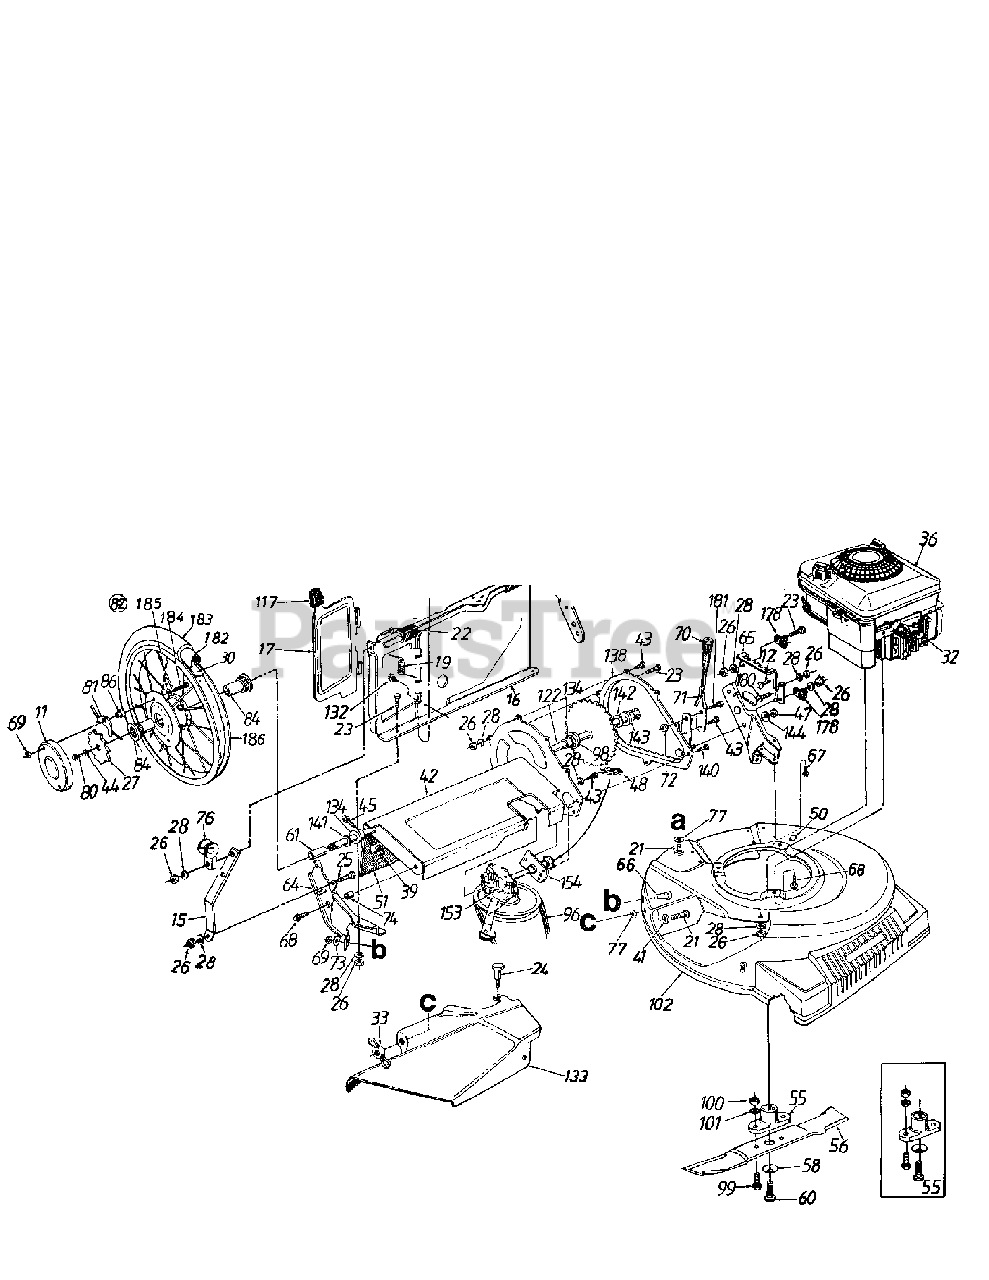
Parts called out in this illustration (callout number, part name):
1	Grip
2	Control Handle Ass'y. L.H.
3	Rope Guide Bolt
4	Truss Mach. Scr. #12 x 1.50" Lg.
5	Rear Discharge Chute Ass'y.
6	3 Tooth Rack Gear Insert
7	Control Panel Half
8	Control Disc Pin
9	Clutch Panel Half
10	Throttle Control Lever
11	Wheel Cover
12	Truss Mach. Scr. 1/4-20 x .62" Lg.
14	Upper Handle
15	Panel Support Brkt.
20	Pivot Pin
21	Carriage Bolt 1/4-20 x .62"
22	Truss Mach. Scr. 1/4-20 x .75" Lg.
23	Hex Bolt 1/4-20 x .5" Lg.
24	Shoulder Bolt Special
25	Hex Bolt 1/4-20 x .62" Lg.
26	Hex Nut 1/4-20 Thd.
27	Wheel Ratchet
28	L-Wash. 1/4" I.D.
30	Rim Strip
31	S.P. Control Cover
32	Spark Plug Insulator
33	Wing Nut
34	Throttle Control Wire 61"
35	Lower Handle
36	Engine
38	Grass Bag
39	Retaining Strip
41	Fl-Wash. .344" I.D. x .62"
42	Rear Support Drive Ass'y.
43	Hex B-Tap Scr. 1/4" x .38"
44	Bell-Wash. 1/4" I.D.
45	Hex AB-Tap Scr. 1/4 x .62"
47	Hex Patch L-Nut 3/8-24 Thd.
48	#48 Chain .500" Pitch x 52 Links
51	Rear Flap
52	Cable Tie (w/Post)
54	Hex AB-Tap Scr. #12 x 1.25" Lg.
55	Blade Adapter Kit
56	21" Blade
58	Bell-Wash. .46" I.D.
60	Hex Bolt 7/16-20 x 1.5"
61	Spacer .628" I.D.
63	L-Wash. 5/16" I.D.
64	Handle Brkt. Ass'y. R.H.
65	Handle Brkt. Ass'y. L.H.
66	Carriage Bolt 5/16-18 x .62"
67	Hex B-Tap Scr. 5/16-18
68	Hex TT-Tap Scr. 3/8-16
69	Hex Nut 5/16-18 Thd.
71	Height Adj. Lever
72	Flanged L-Nut 3/8-16 Thd.
73	Bell-Wash. 5/16" I.D.
74	Spacer .383" I.D.
76	Rope Guide
77	Bolt Retainer 1/4 x .50" O.D.
79	Control Label
80	Hex Bolt 1/4-20 x .75" Lg. (Grade 5)
81	Pawl and Spring Ass'y.
82	Wheel Ass'y. Comp.
84	Flange Bearing 63" I.D.
86	Special Hex Nut 5/16-18 Thd.
87	Panel Clip
95	S.P. Cable 50" Lg.
96	"V"-Belt
97	Bag Handle
98	Spacer 63" I.D. x 1.25"
99	Hex Bolt 3/8-24 x 1.0" Lg.
100	Hex Nut 3/8-24 Thd.
101	L-Wash. 3/8" I.D.
115	Self-Propelled Control Cover
116	Control Lever
117	Door Grip
118	Fl-"C"-Sunk Hd. Tap Scr. #10 x .75" Lg.
121	Curved Carr. Bolt 5/16-18 x 1.38" Lg.
122	Sprocket and Axle Ass'y.
129	Control Cable 39"
131	Intern. Cotter Pin 1/8" Dia.
132	Hex B-Tap Scr. #10 x .38" Lg.
133	Side Chute Deflector Ass'y.
134	Hex Flange Bearing
135	Kit Control Housing Comp.
138	Chaincase and Arm Ass'y.
140	Hex S-Tap Scr. 1/4-20 x .50"
141	Fl-Wash. .632" I.D. x .943"
142	Fl-Wash. .635" I.D. x 1.0"
143	Hex Flange Brg. .631" I.D.
144	Fl-Wash. .385" I.D. x .87"
153	Transmission Comp. (See Breakdown)
156	Plastic Tubing
164	Spd. Control Cable 50" Lg.
165	6-Spd. Shift Lever
169	Cot-Pin 3/32" Dia. x .75" Lg.
170	Shift Rod
171	Movable Pulley Half Ass'y.
172	Carr. Bolt 1/4-20 x .5" Lg.
173	Splined Pulley Half
174	Flanged Bushing
175	Fl-Wash. .328" I.D. x .68" O.D.
176	Cable Mtg. Brkt. Ass'y.
177	Shift Lever Spring
178	Clamp
179	6-Spd. Rack Cable Brkt.
180	Truss Mach. Scr. 1/4-20 x .75" Lg.
181	Hex Bolt 3/8-16 x .62" Lg.
182	Inner Tube 16" x 2.12"
183	Chevron Tire 16" x 2.125"
184	Hex Bolt Special 5/16-18 x 1" Lg.
185	Intern Lock Wash. 5/16" I.D.
186	Rim Ass'y. Only 16" x 2.1"
